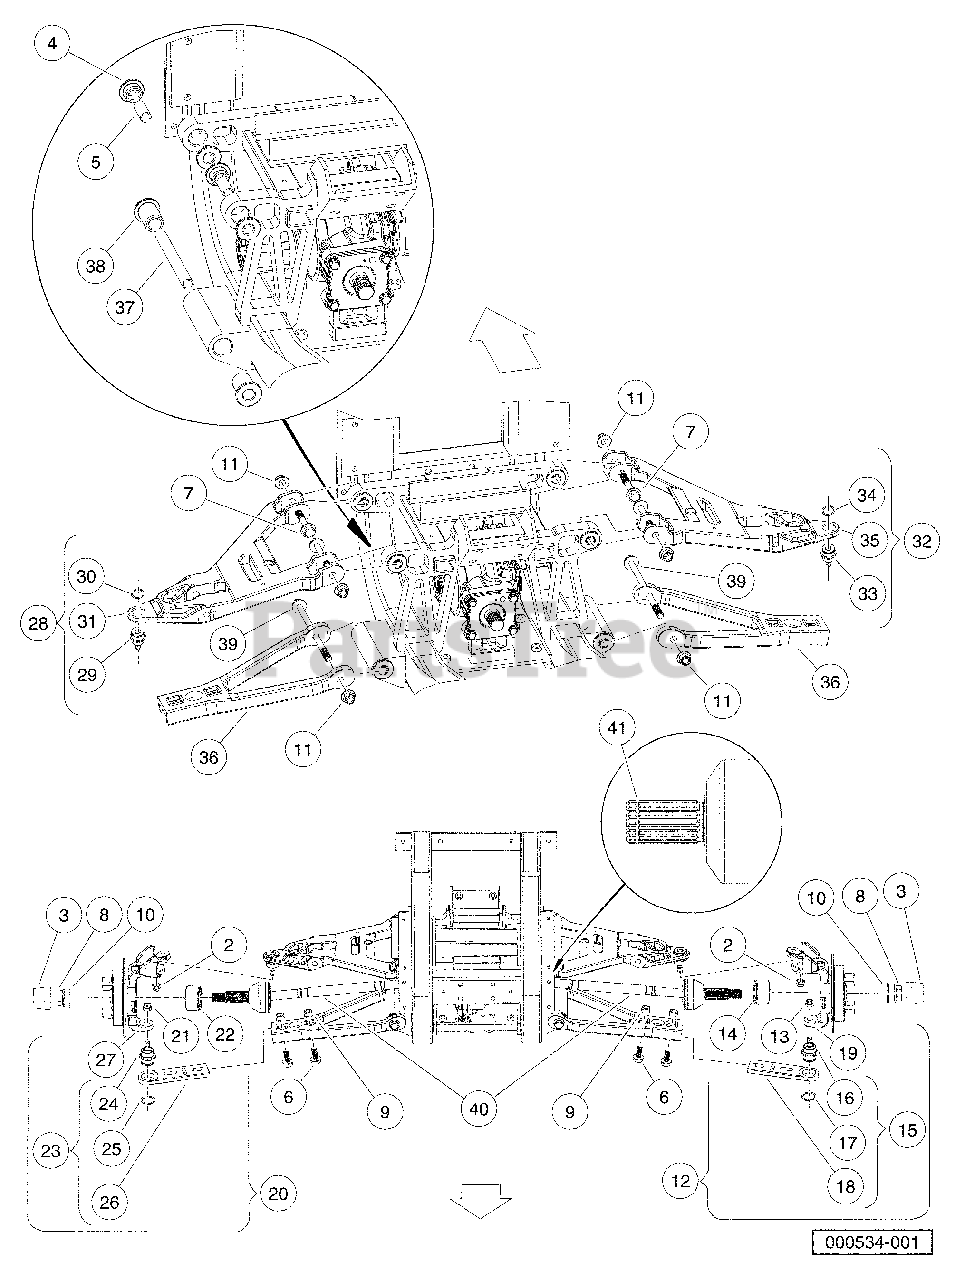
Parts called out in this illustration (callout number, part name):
1	Suspension, AWD, Wide
2	Locknut, M12-125 Nylon
3	Center Cap, Rubber
4	Bushing, A-Arm
5	Sleeve, Upper
6	Bolt, Flange Head, M12x 175x 30 with Loctite
7	Bolt, Flange Head, M12 X 175 X 70
8	Nut Flg, M22 X 15 Mech Def
9	Nut, Square, M12x 175
10	Washer Hard, M22
11	Nut Flg, M12x175, Nylon Gr 10
12	Upright, Left-Hand
13	Locknut, M12-125 Nylon
15	Asm, Adjuster, Slide
16	Joint, Ball
17	Ring, Retaining, Ext, 1-1/4"
18	Slide, Adjuster
19	Upright, Finished, Lh
20	Upright, Right-Hand
21	Locknut, M12-125 Nylon
23	Asm, Adjuster, Slide
24	Joint, Ball
25	Ring, Retaining, Ext, 1-1/4"
26	Slide, Adjuster
27	Upright, Finished, Rh
28	Asm, A-Arm, Upper, Left
29	Joint, Ball
30	Ring, Retaining, Ext, 1-1/4"
31	Arm, Upper, Wide, Machined, Lh
32	Asm, A-arm, Upper, Right
33	Joint, Ball
34	Ring, Retaining, Ext, 1-1/4"
35	Arm, Upper, Wide, Machined,rh
36	A-Arm, Lower
37	Sleeve, Lower Arm
38	Bushing, Lower Arm
39	Bolt Flg, M12 X 175 X 200 10
40	Half Shaft, Wide, Awd
41	Ring, Hog, Half Shaft
